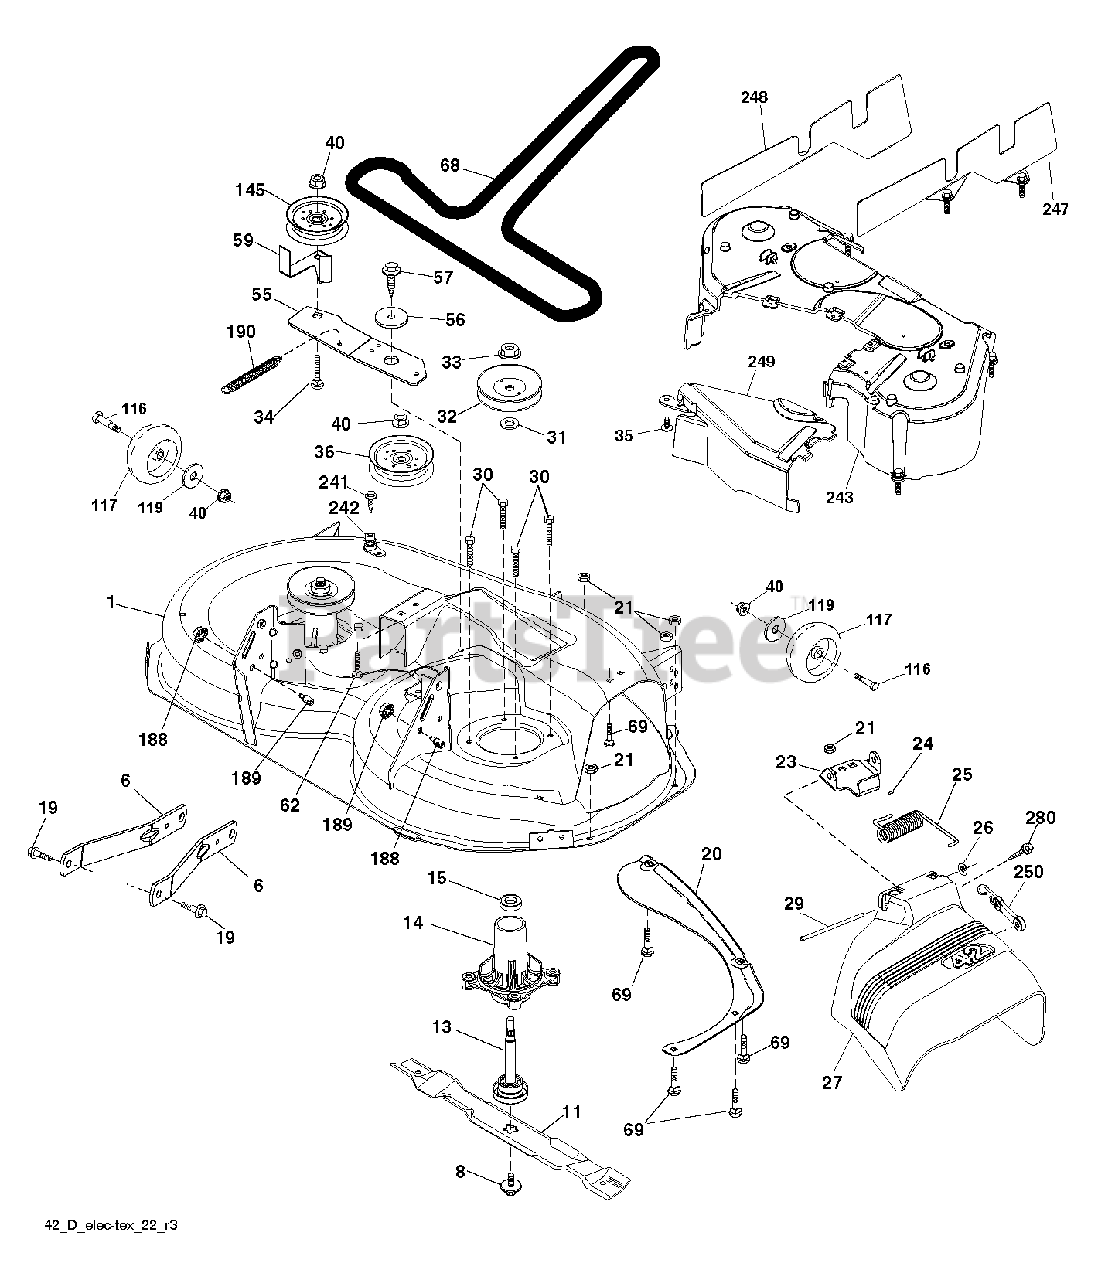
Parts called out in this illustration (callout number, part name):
6	ARM.SUSPENSION.MOWER.R
8	BOLT.WASHER.ASM.7/16-2
11	42" HI-LIFT BLADE
13	SHAFT.ASM.MDRL.N/GREASE.38
14	HOUSING.MANDREL.4PT.
19	BOLT.SHOULDER
20	BAFFLE.VORTEX
21	LOCKNUT
23	BRKT.DEFLECTOR.38"2005+
24	CAP-SLEEVE LT
25	SPRING.TORSION.DEFLECT
26	NUT PUSH M
27	DEFLECTOR ASM.42"TEX.FRENCH
29	ROD.HINGE
30	SCREW, WASHER HEAD
31	WASHER.SPACER.MANDREL
32	PULLEY/MANDREL
33	NUT.FLANGE.LOCK.TOP
34	BOLT.3/8-16X1.50
35	FASTENER.XMAS.TREE
36	PULLEY.IDLER.2006
40	NUT LOCK FLG 3/8-16 UNC
55	IDLER.ARM.42"
56	SPACER.RETAINER
57	SCREW 3/8-16X1
59	GUARD, BELT
68	BELT V SECONDARY
69	BOLT
116	BOLT M
117	WHEEL.GAGE.HALF.SPOKED
119	WASHER
145	PULLEY.IDLER.48"PRIMARY
188	STUD.FASTNER.W/ANTI-ROTATE
189	NUT LOCK HEX FLANGE 5/16-18
190	SPRING.MOWER.DRIVE.ELECTRIC
241	SCREW.TT.#10-32X.5.3/8.FLANGE
242	PORT.WASHOUT
243	COVER DECK
247	SHIELD RIGHT
248	SHIELD LEFT
249	COVER CABLE CLUTCH
250	ELASTIC STRAP KIT
280	SCREW 3/8-16X1/2
